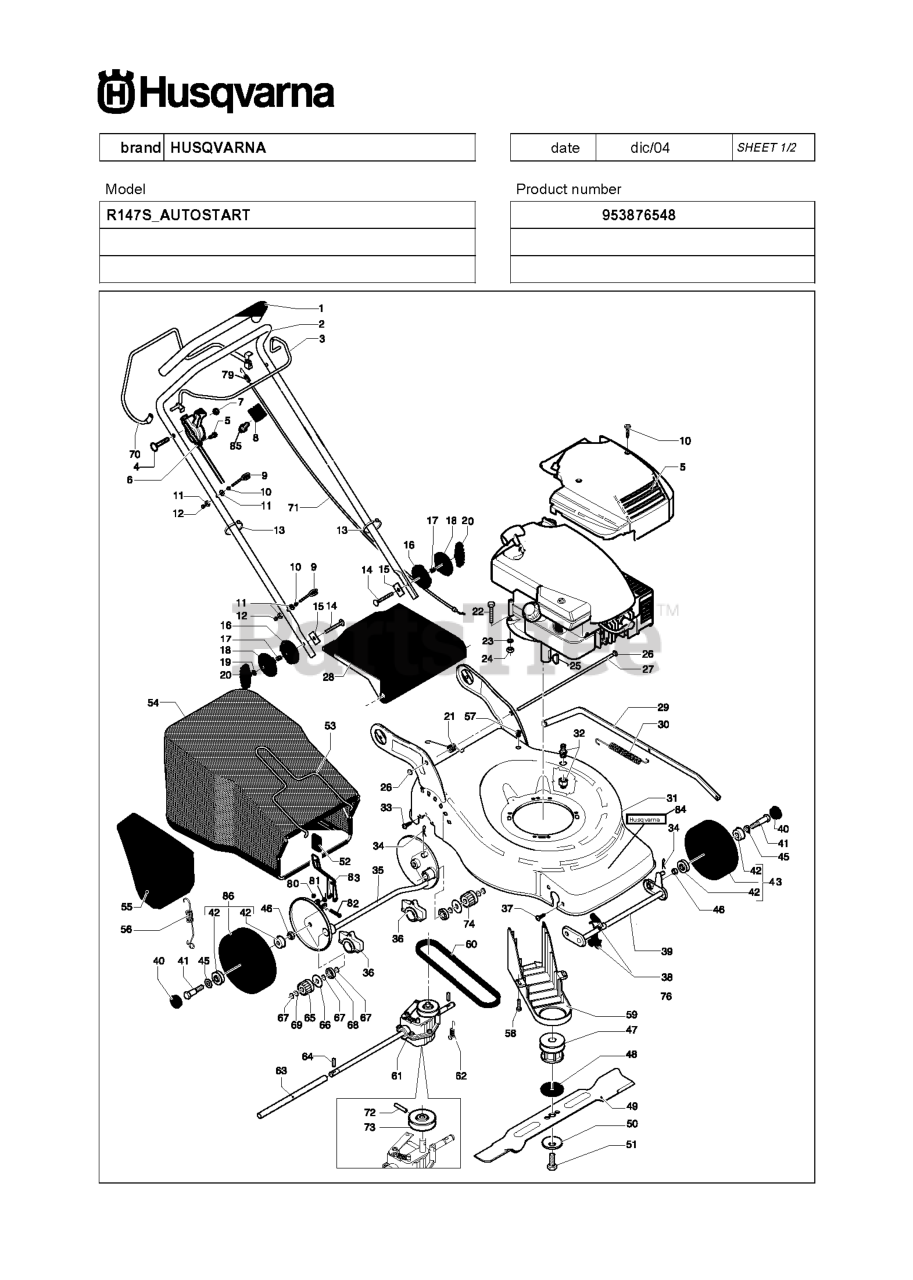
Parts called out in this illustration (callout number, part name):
1	WIRE ASM INNER W/ PLUNGER LT
2	SHAFT ASM R HANDLE
3	PIN GROOVE.
4	RETAINING RING LT
6	BEARING.NYLON
8	PLUNGER BUT KIT
11	LINK LIFT LH
12	LINK LIFT RH
13	RETAINER-SPRNG RB
15	LINK.SUSPENSION.FRONT
16	NUT.HEX.JAM.1/2-13
18	NUT.LK.W/WSH.1/2.
19	ARM.REAR.SUSPENSION
20	PIN.COTTER.7/16.BOW TI.
31	BEARING.PIVOT.LIFT
32	NUT CROWNLOCK 3/8-24
55	PIN.COTTER.5/16.BOW TI
